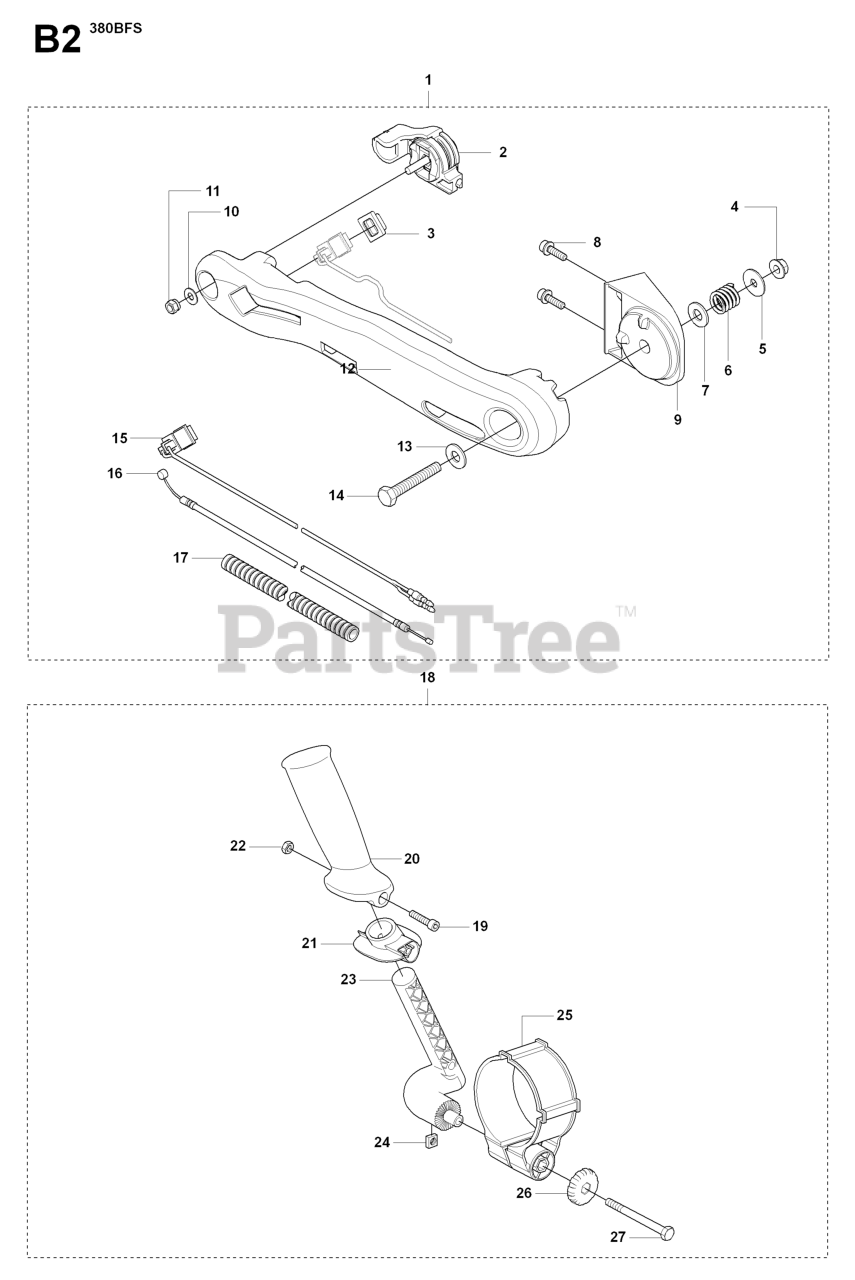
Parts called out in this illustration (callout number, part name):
1	LEVER
2	LEVER
3	CAP
4	NUT
5	WASHER
6	SPRING
7	WASHER
8	SCREW
9	RP_BRACKET
11	NUT
12	ARM
13	WASHER
14	BOLT
16	CABLE COMP
19	SCREW
23	BRACKET
25	HOLDER TH
